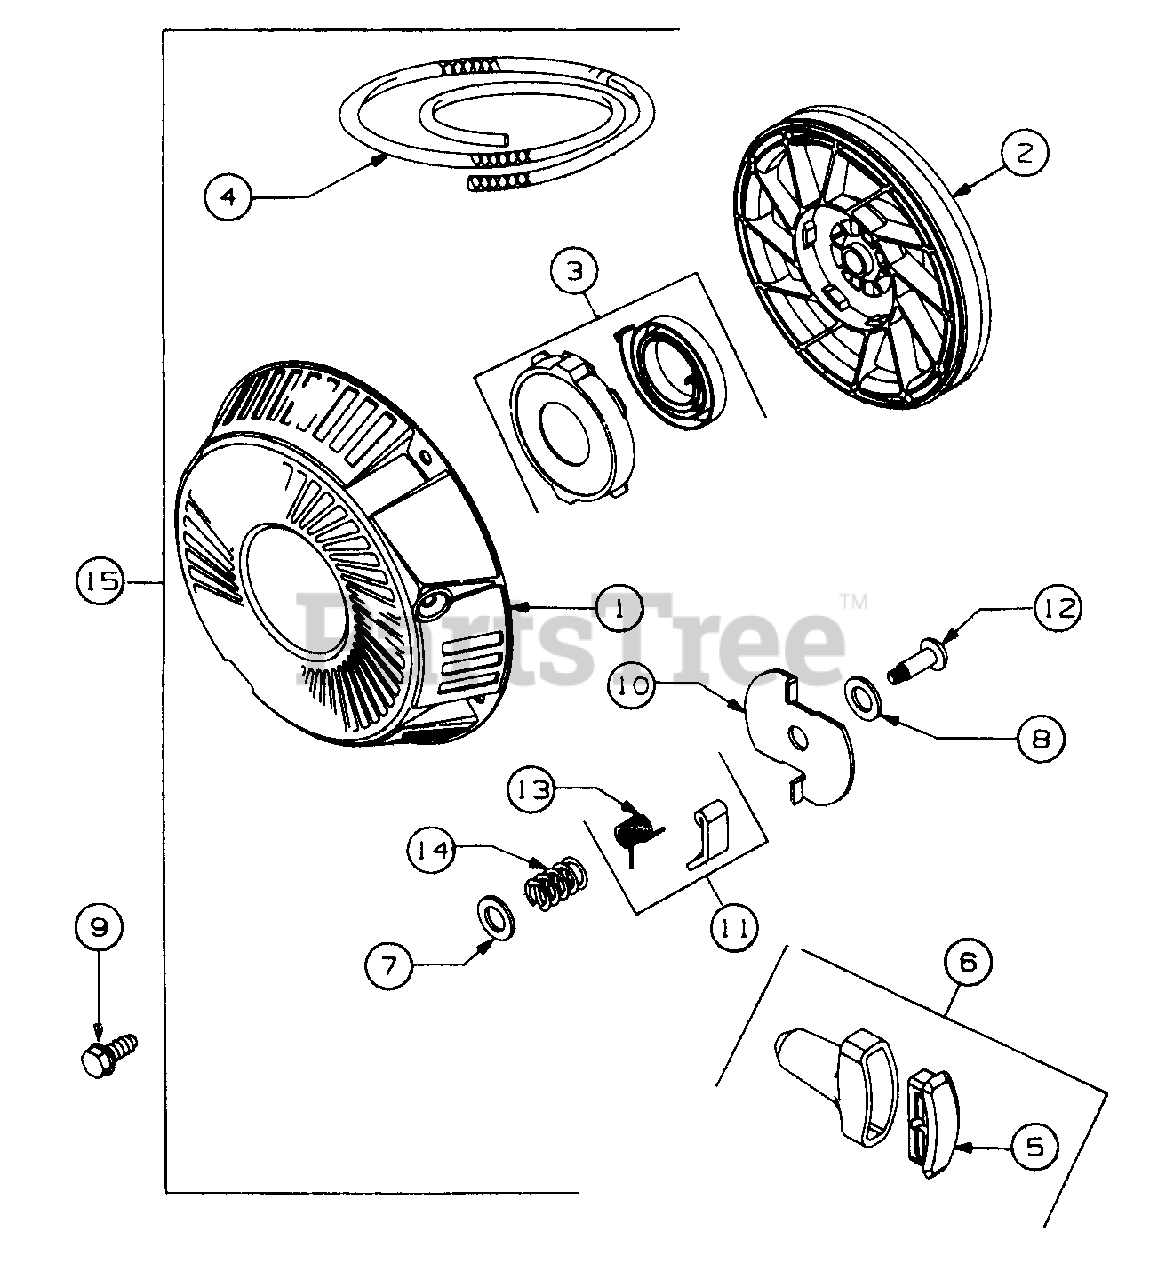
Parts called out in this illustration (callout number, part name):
1	Housing, Rewind Starter
2	Pulley, Rewind Starter
3	Spring, Rewind Starter
4	Rope, Starter (Cut to 69-1/2)
5	Insert, Starter Handle
6	Handle, Rewind Starter
7	Washer, Pulley
8	Washer, Retainer
9	Screw, Sem
11	Dog, Starter
12	Screw, Retainer
13	Spring, Dog
14	Spring, Torsion
15	Starter Assy, Rewind
